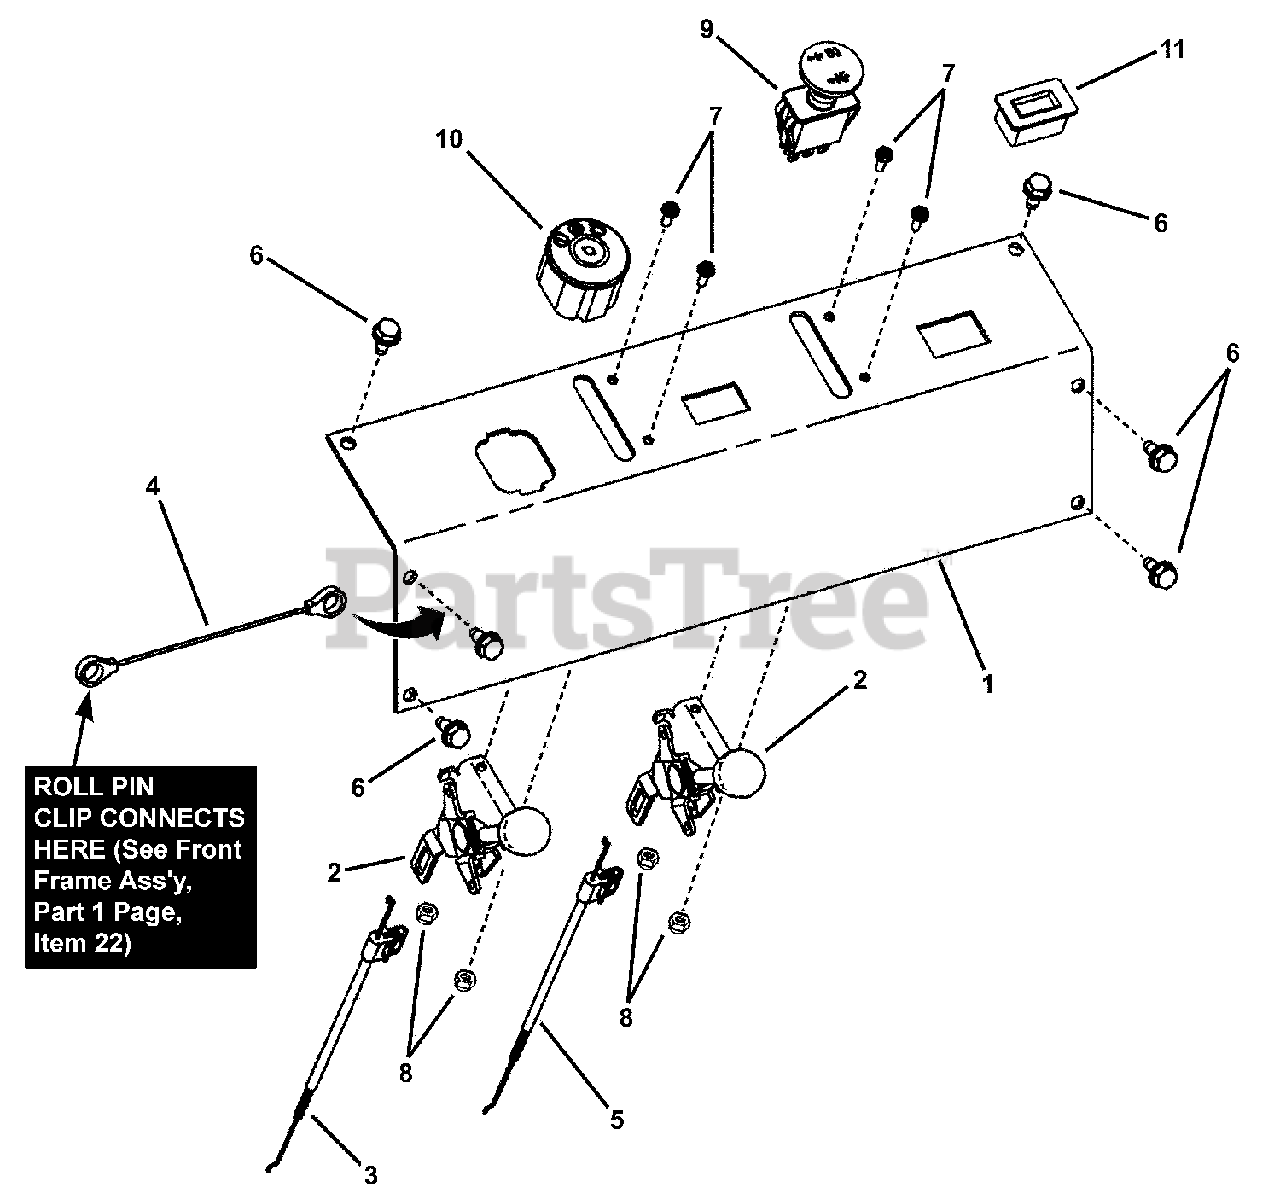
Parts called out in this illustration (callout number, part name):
1	CONTROL PANEL
2	CONTROL LEVER, Throttle/Choke
3	CONTROL CABLE, Throttle
4	STRAP, Tether
5	CONTROL CABLE, Choke
6	SCREW, 5/16-18 x 5/8" Hex Washer Self-Tap
7	SCREW, #10-32 x 5/8" Hex Washer Self-Tap
8	NUT, #10-32 Nyloc
9	SWITCH, PTO, Yellow
10	SWITCH, Ignition
11	HOUR METER w/Flash Alerts
